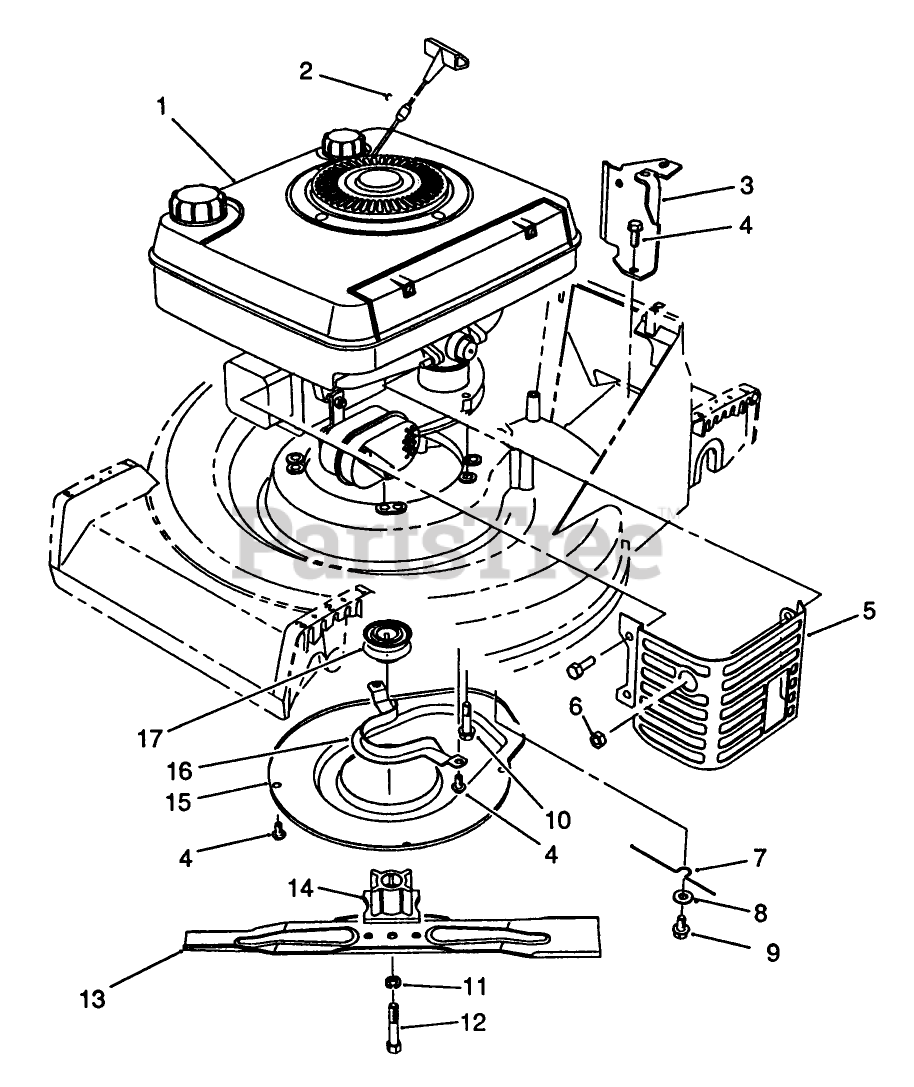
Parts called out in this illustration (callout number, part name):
2	Staple-Rope Stop
3	Bracket-Cable Support
4	SCREW-HWHTF
5	Heat Shield-Muffler
6	NUT - LOK,KEPS 1/4-28NF
7	RETAINER-BELT
8	WASHER-FLAT
9	SCREW-HHFTF
10	SCREW-HWHTF
11	WASHER-LOCK
12	SCREW-BLADE
13	Key
14	BLADE RETAINER
15	Cover
16	Guide-Belt
17	PULLEY-DRIVE, ZONE START
